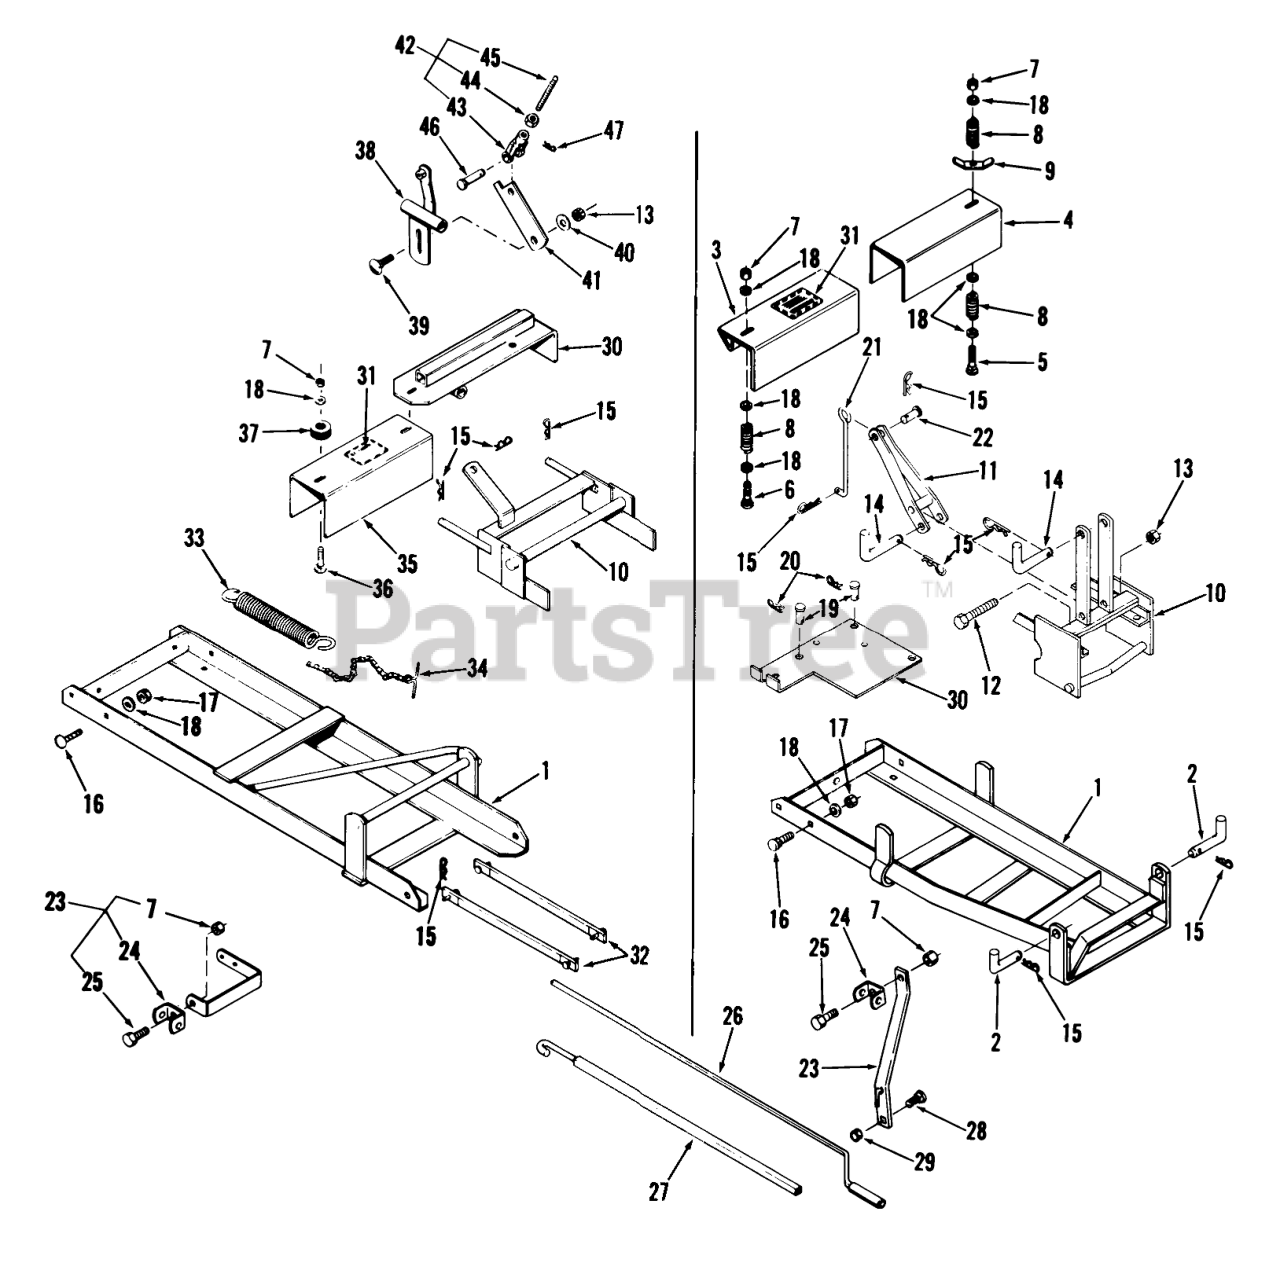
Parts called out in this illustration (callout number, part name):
1	Mounting Frame
3	PTO Cover (Top)
4	PTO Cover (Bottom)
5	Bolt
6	BOLT
7	Nut
8	SPRING
9	Wing Bracket
10	Gearbox MountingBracket
10	ASSEMBLY-BRACKET
11	Bell Crank Assembly
12	Bolt 1/2-13 x 3 1/2
13	Eslok Nut
15	Pin
16	Bolt
16	Bolt-Carriage
18	Washer
20	Pin
23	Crank Rod Support
23	Crank Rod Support Assembly
24	Crank Rod Guide
25	BOLT
26	Crank Rod
27	Crank Rod Extension
28	Bolt
29	Keps Nut 5/16-18
30	Gearbox Mounting Plate
30	Assembly-Gearbox Mtg.
31	Decal
32	Lift Bar
33	SPRING-EXTENSION
34	Chain and Toggle
35	PTO Cover
36	Carriage Bolt
37	Rubber Washer
38	Bracket-Gearbox Actuating
39	CARRIAGE BOLT -4
40	Washer
41	NDNK-OVER CENTER
42	Turnbuckle Assembly
44	Nut
45	Stud
46	Clevis Pin
47	PIN-HAIR
